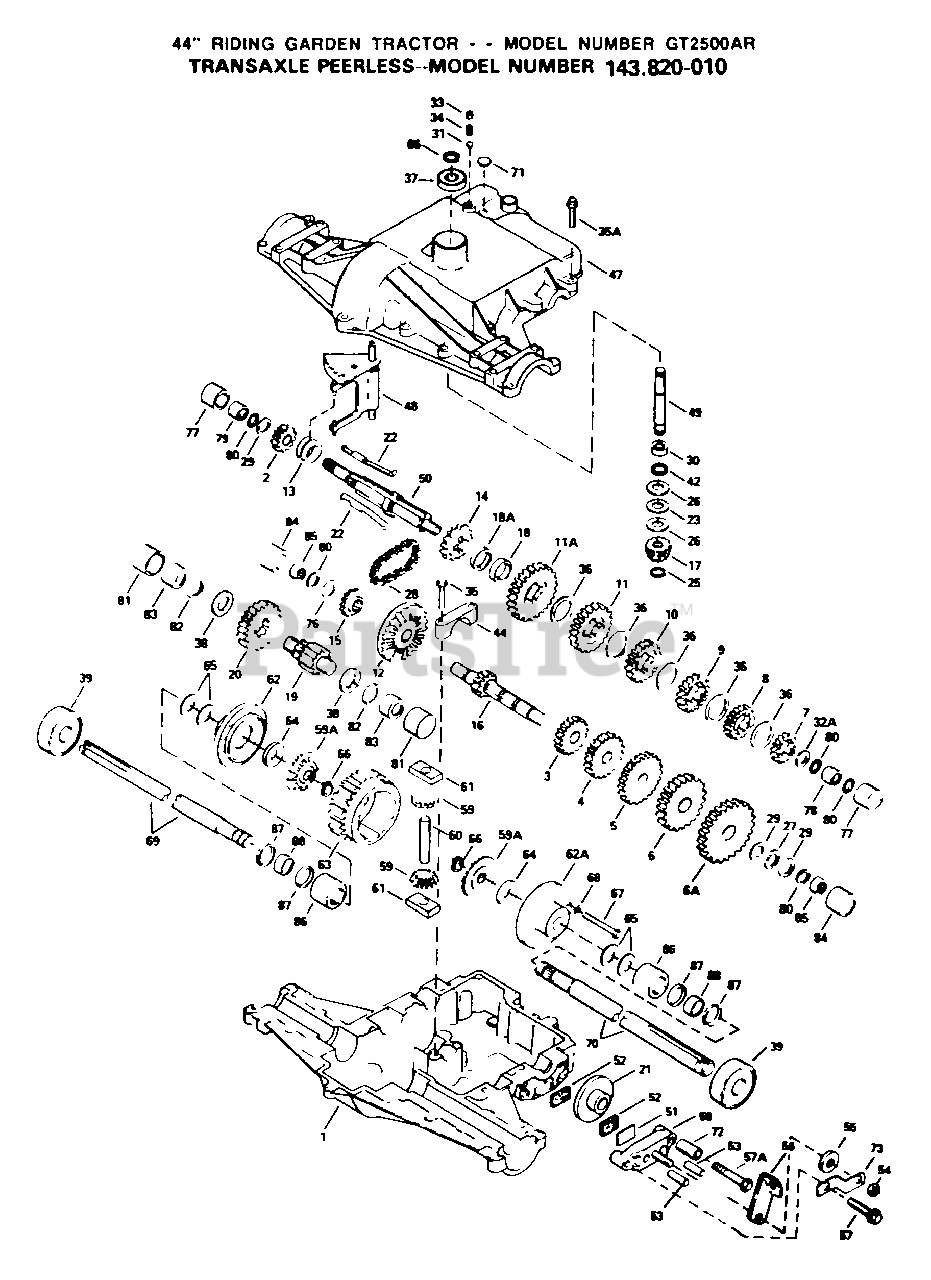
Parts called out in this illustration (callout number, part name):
1	CASE TRANSAXLE
2	GEAR, SPUR, 15T
3	GEAR, SPUR, 12 TEETH
4	GEAR, SPUR, 15T
5	GEAR, SPUR, 20T
6	GEAR, SPUR, 28T
6A	GEAR, SPUR, 31T
7	GEAR, SPUR, 19 TEETH
8	GEAR, SPUR 22T
9	GEAR, SPUR (30 TEETH)
10	GEAR, SPUR (35 TEETH)
11	GEAR, SPUR 37T
11A	GEAR, SPUR (41 TEETH)
12	GEAR BEVEL, 33T
13	COLLAR SHIFT
14	SPROCKET 18T (REV)
15	SPROCKET 9T
16	SHAFT COUNTER
17	BEVEL PINION, 13T
18	SPACER, .350/.340 THICK
19	SHAFT, OUTPUT, 9T
20	GEAR, OUTPUT, 35T
23	BEARING THRUST
25	RETAINING RING
26	RACE, THRUST
27	THRUST BEARING
28	CHAIN, ROLLER
29	WASHER THRUST
30	BEARING NEEDLE
31	BALL STEEL, 5/16" DIA.
32A	WASHER, THRUST
33	SCREW, 3/8-16 X 3/8"
35	SCREW, 1/4-20 X 1-1/4
35A	SCREW HEX HD 5/16-18 X 1-1/4
36	WASHER THRUST
37	BEARING BALL
38	WASHER THRUST
39	BEARING BALL
42	OIL SEAL 3/4
44	BEARING CAP
47	COVER, TRANSAXLE
48	ROD AND FORK ASSY SHIFT
49	SHAFT INPUT
51	PLATE BRAKE PAD
54	LOCKNUT 5/16-24
55	WASHER, FLAT
56	LEVER BRAKE
57	SCREW, 1/4-20 X 1-1/4
57A	SCREW FLNG HEX 1/4-20 X 2-1/4
58	HOLDER BRAKE PAD
59	PINION, 10T
61	BLOCK DRIVE
62	CARRIER DIFF THREADED HOLES
62A	CARRIER DIFF
63	GEAR, RING, 31T
65	WASHER THRUST
67	SCREW, 1/4-20 X 2-1/4
68	WASHER LOCK 1/4
69	AXLE, 12-5/16" LONG
70	AXLE, 16-3/16" LONG
71	PLUG, THRDED, 9/16-18
73	BRKT BRAKE LEVER
78	BEARING NEEDLE
79	BEARING NEEDLE
82	RING SQ CUT
83	BEARING, NEEDLE
85	BEARING NEEDLE CAPPED
87	RING SQ CUT
88	BEARING NEEDLE
